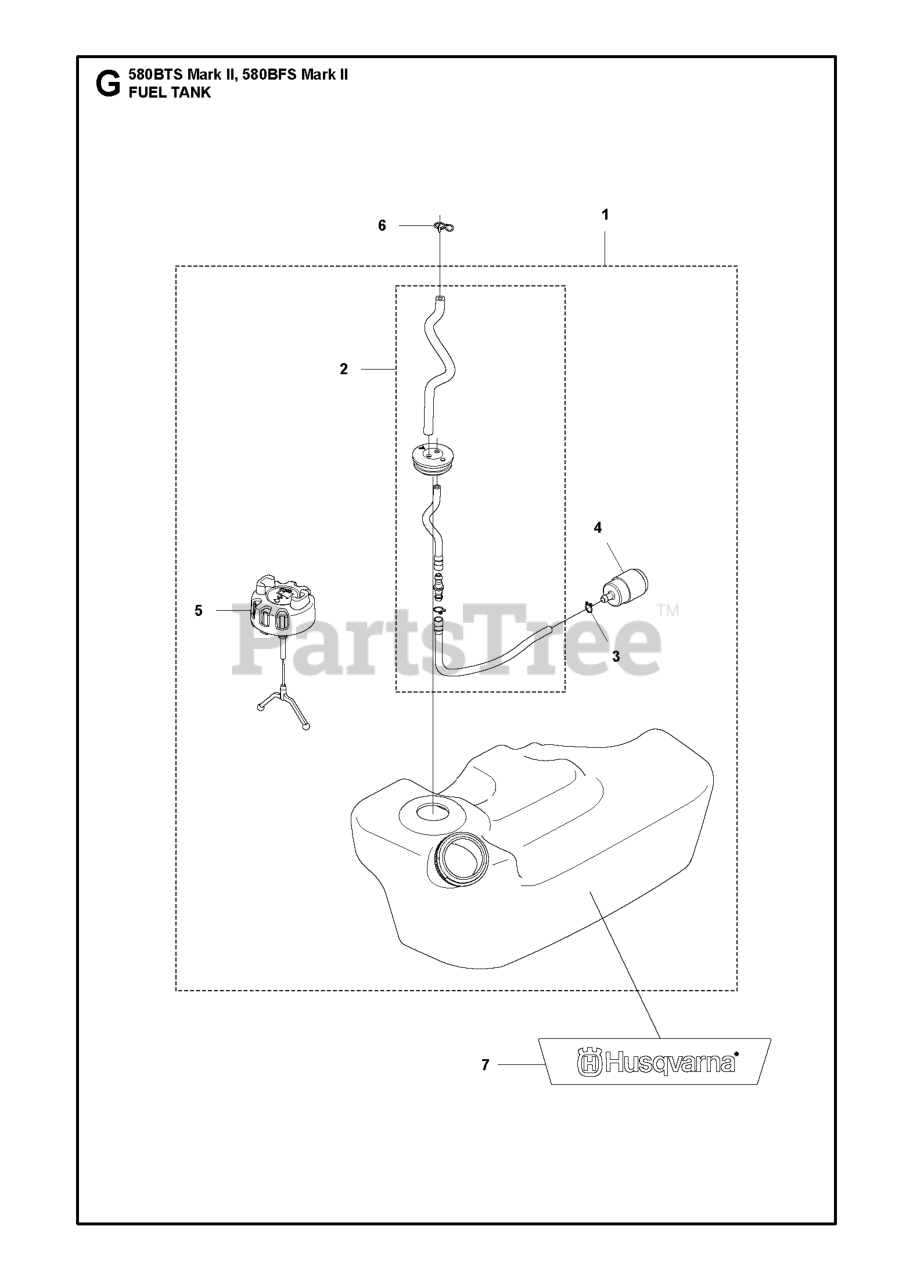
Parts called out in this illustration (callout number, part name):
2	PIPE ASSY
4	FILTER ASSY
5	FUEL CAP ASSY
